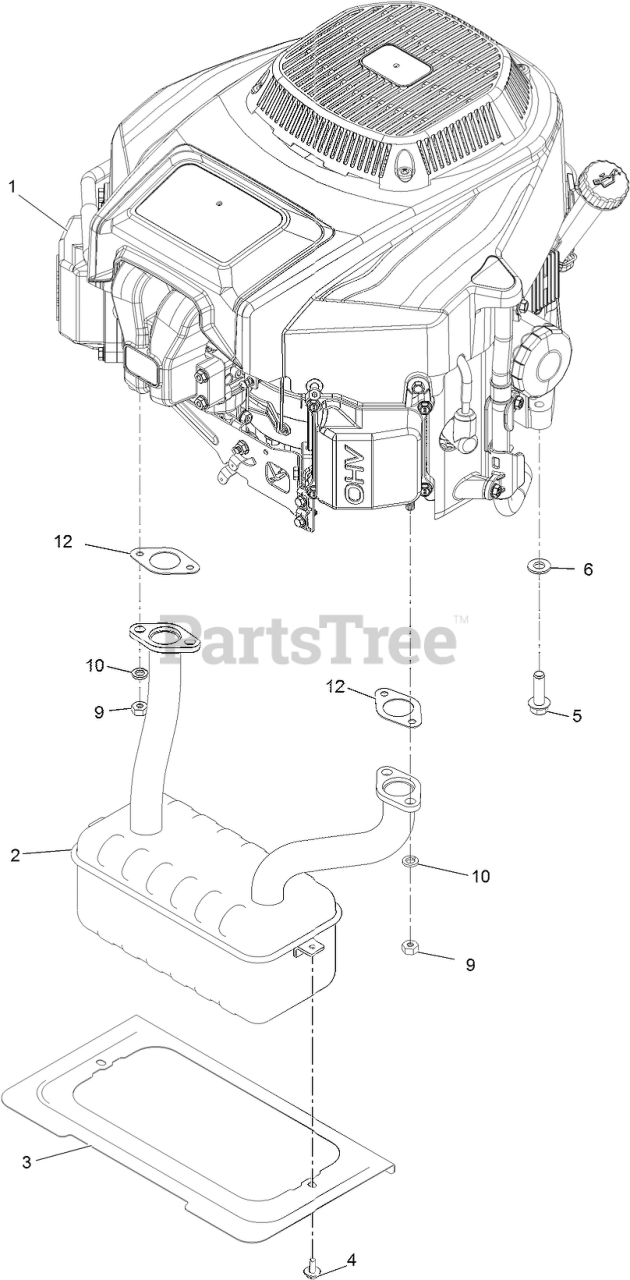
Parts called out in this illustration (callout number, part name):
1	Engine-2P77F
2	MUFFLER
3	SHIELD-HEAT
4	SCREW-HHFTF
5	SCREW-THD
6	WASHER-FLAT
10	WASHER-LOCK, SPLIT
12	GASKET-EXHAUST
